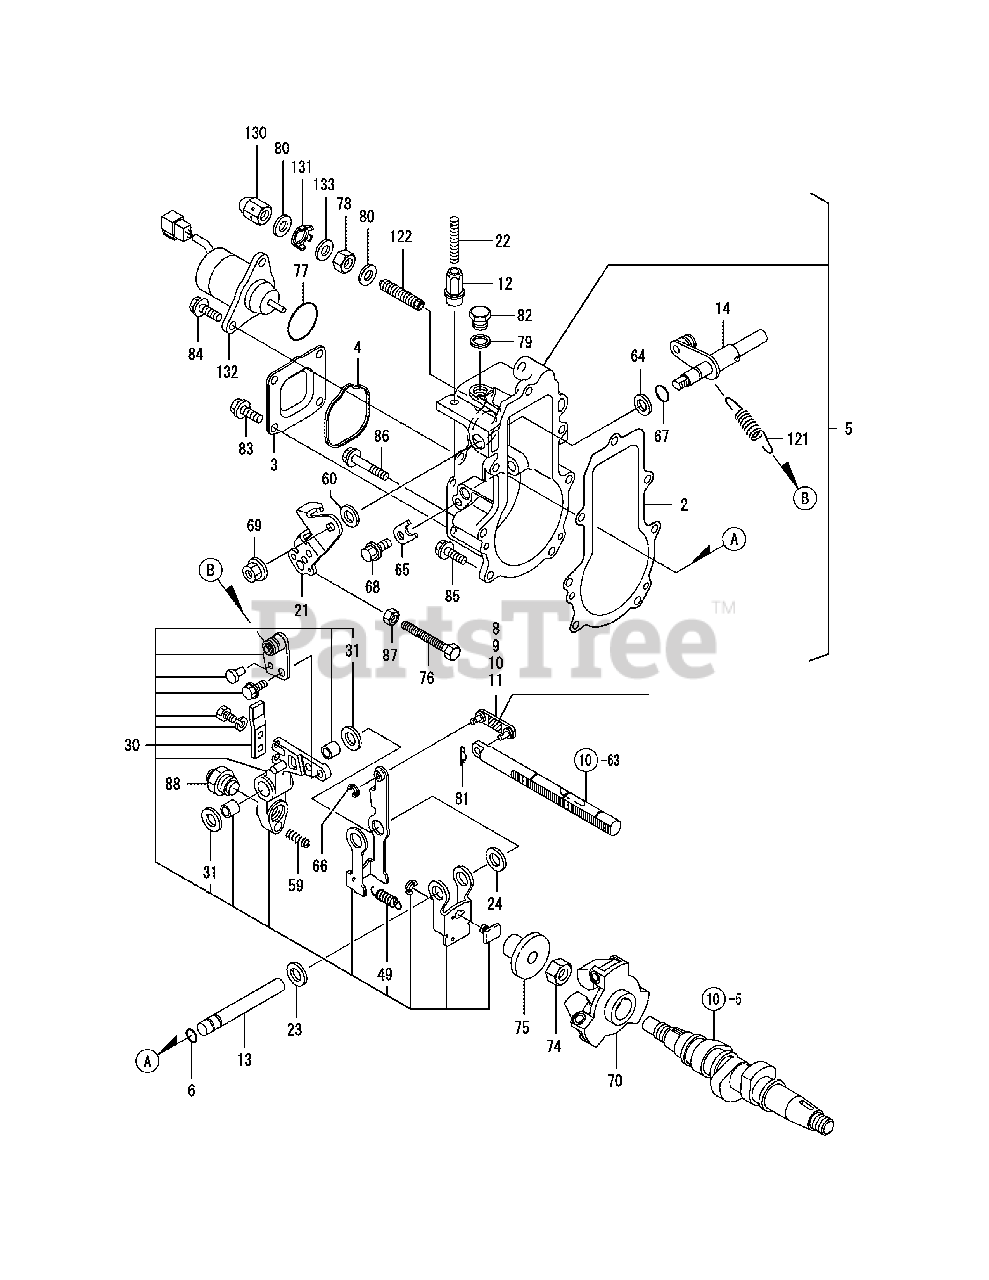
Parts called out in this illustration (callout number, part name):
3	Case, Governor
5	Case Assembly, Governor
13	Shaft, Gov. Lever
14	Shaft Assembly, Control
21	Lever, Control
22	Bolt, Revol. Limit
24	Spacer Assembly
30	Lever Assembly, Governor
59	Spring, Fuel Control
65	Retainer, Shaft
68	Bolt, 6 x 10 Plated
70	Weight Assembly
74	Nut, Governor Weight
76	Bolt, Idle Limit
83	Bolt, 6 x 10 Plated
84	Bolt, M 6 x 14 Plated
85	Bolt, M 6 x 20 Plated
86	Bolt, M 6 x 45 Plated
88	Angleich Assembly
121	Spring, Governor
122	Limiter Assembly, Fuel
132	Solenoid, Stop
